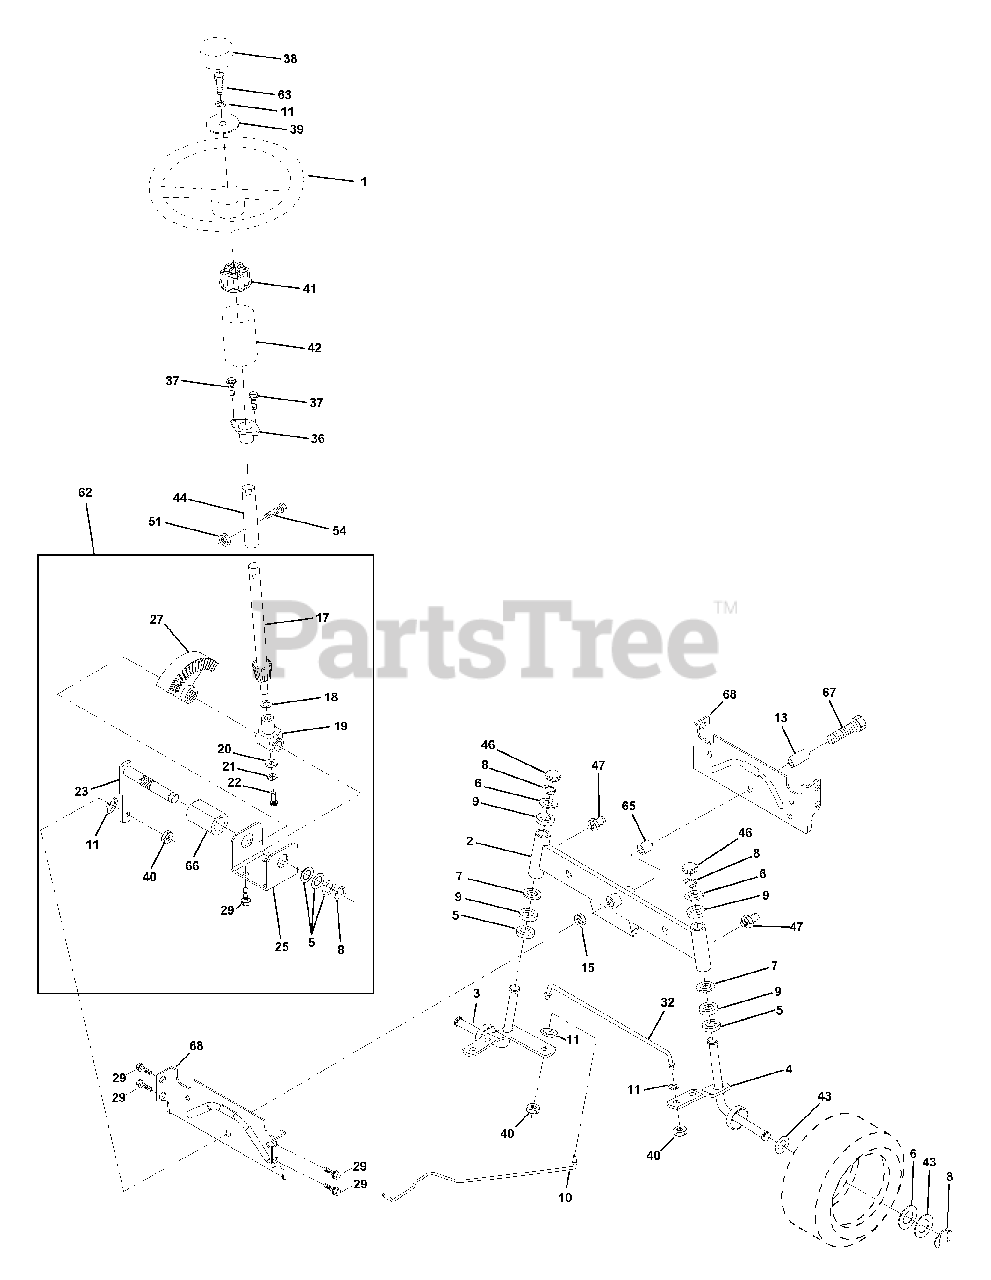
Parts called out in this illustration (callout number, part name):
1	Wheel Steering
2	Axle Front Casting Machine
3	Spindle Asm LH Cast
4	Spindle Asm RH Cast
5	Bearing Race Thrust Harden
6	Washer 25/32 X 1-5/8 X 16 Ga
7	Washer 27/32 X 1-1/4 X 16 Ga
8	Ring Klip #t5304-75
9	Bearing Col Strg Blk
10	Link Drag Extended Cast
11	Washer Lock Hvy Hlcl Spr 3/8
13	Bearing Axle STLT/GT
15	Nut Lock Flange 5/8-11 Unc
17	Shaft Asm Strg
18	Washer Thrust 515x 750x 033
19	Support Shaft
20	Washer Shim 1/4 X 5/8 X 062
21	Washer Lock Hvy Helical 1/4
22	Screw Cap Sckt Hd Phos & Oil
23	Shaft Asm Pittman
25	Bracket Steering
27	Gear Sector
29	Screw Thdrol 3/8-16x3/4 Ty-tt
32	Rod Asm Tie Ball J Adj VGT
36	Bushing Strg
38	Insert Cap Strg Wh Au
39	Washer 13/32 X 2-3/8 X 8 Ga
40	Lock nut
41	Adaptor Wheel Strg
42	Boot Steering Shaft
43	Washer 25/32 X 1 1/4 X 16 Ga
44	Extension Steering Shaft LR/LT
46	Cap Spindle Fr Top Blk
47	Fitting Grease
51	Nut Lock Hex w/Ins 5/16-18
54	Bolt Fin Hex 5/16-18 Unc x 1-1/4
62	Kit, Steering Assembly Svc
63	Bolt Fin Hex 3/8-16unc x 1 Gr. 5
65	Spacer Axle
66	Bearing Arm Pittman
67	Bolt, Fin Hex 5/8-11 UNC x 2-3/4
68	Axle, Brace
